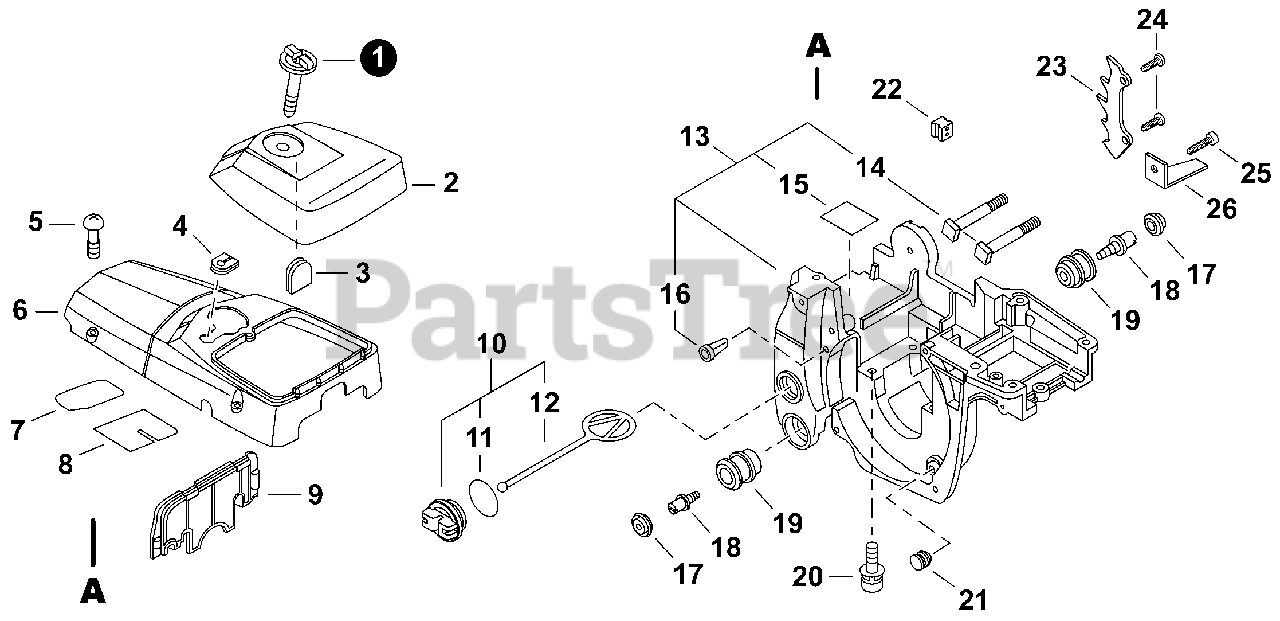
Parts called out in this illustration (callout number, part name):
1	THUMBSCREW
2	COVER, AIR FILTER
4	GROMMET
5	SCREW 5×20
6	COVER, ENGINE
7	SHIELD, HEAT
8	SHIELD, HEAT
9	PLATE, INSULATOR
10	CAP ASSY
11	O-RING 25
12	CONNECTOR, CAP L= 60mm
13	COVER ASSY, ENGINE
14	STUD, GUIDE BAR 8
15	SHIELD, HEAT
16	VENT ASSY
17	CAP, CUSHION
19	CUSHION 5
20	BOLT 5×30
21	CUSHION
22	GROMMET, LEAD
23	SPIKE, BUMPER
24	SCREW TAPPING 5×20
25	SCREW TAPPING 5×16
26	CHAIN CATCHER
